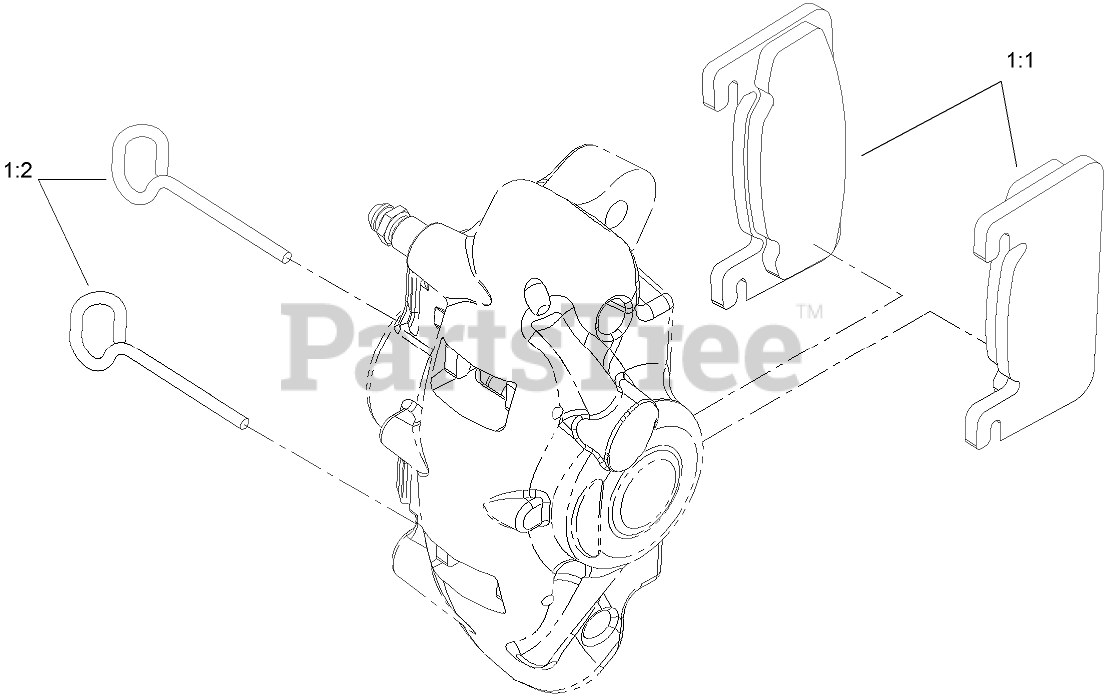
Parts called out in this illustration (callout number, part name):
1	FRICTION PAD AND PIN KIT
1:1	BRAKE PAD ASM
1:2	Pin
